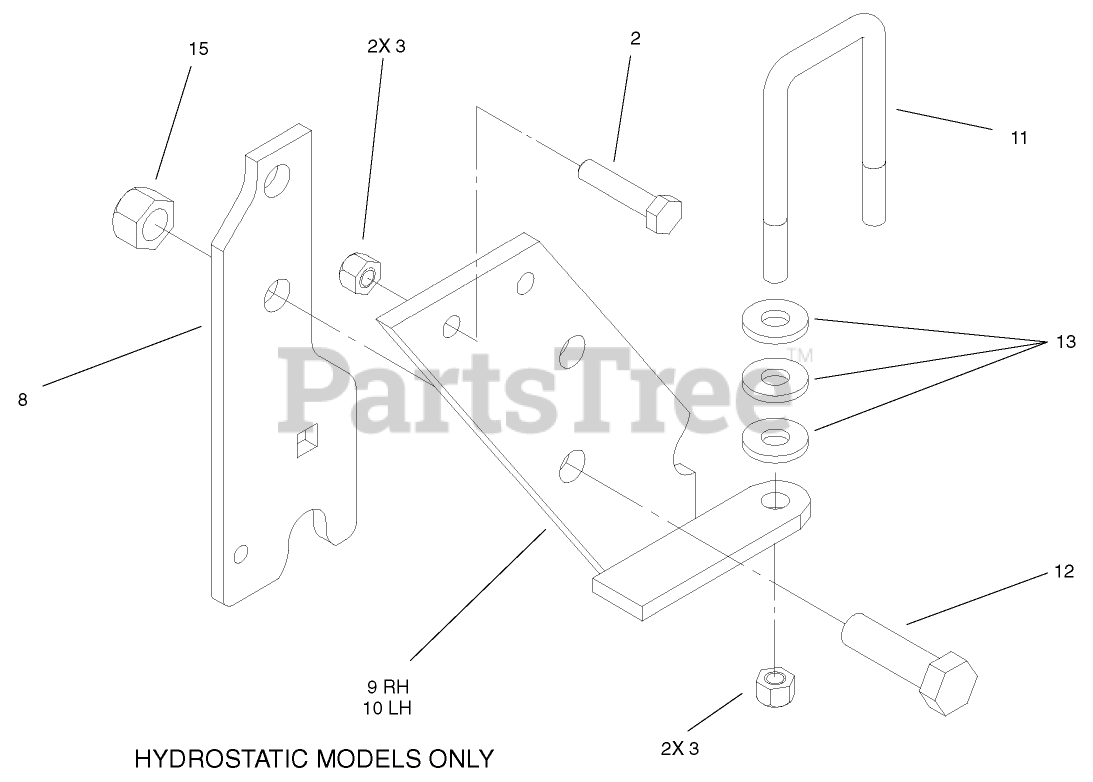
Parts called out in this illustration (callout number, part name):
2	SCREW-HH
3	NUT-LOCK, NI
8	BRACKET-HITCH
9	PLATE-HITCH
10	PLATE-HITCH
11	U-BOLT
12	SCREW-HH
13	WASHER-SPACER
15	NUT-LOCK, NI
